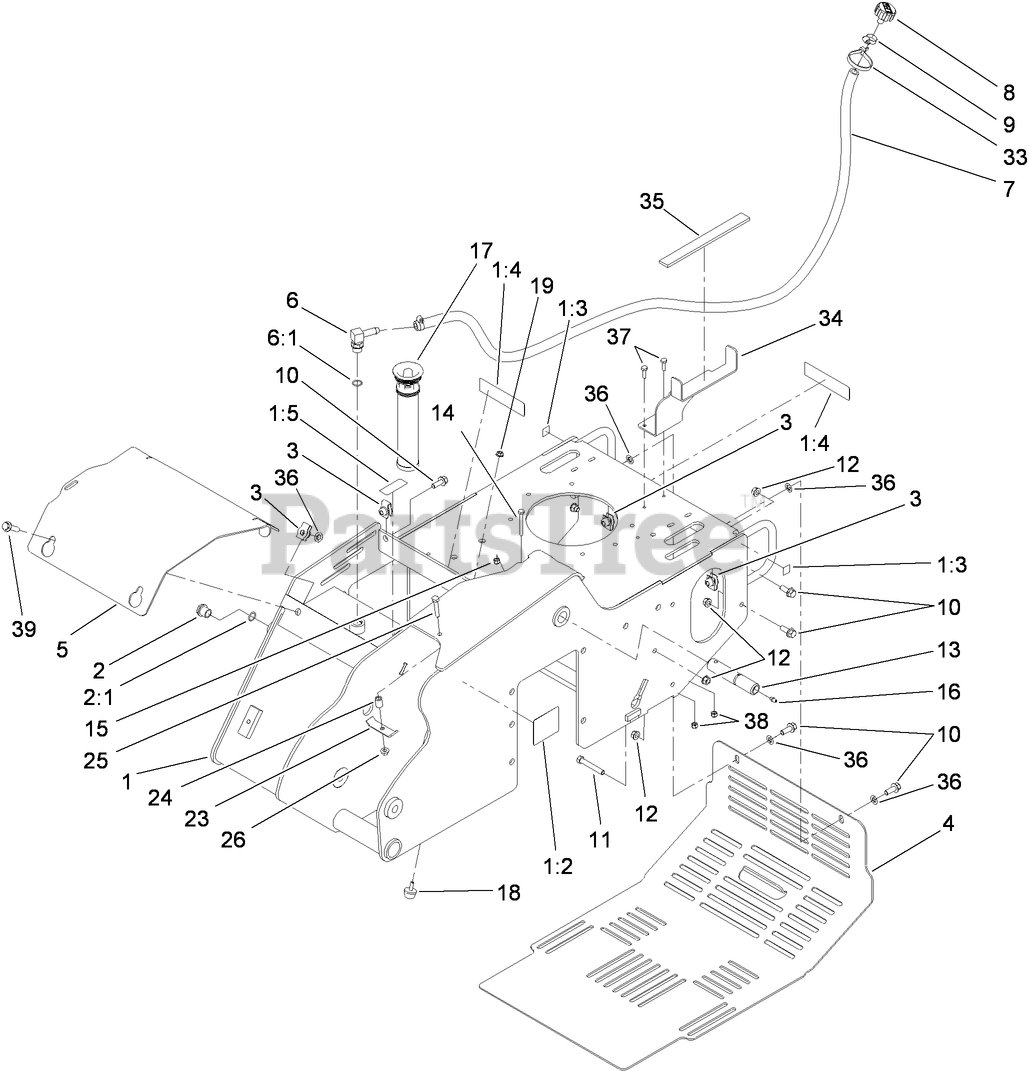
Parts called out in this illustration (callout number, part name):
1	MAIN FRAME ASM
1:2	DECAL-WARNING
1:3	DECAL-POINT, LIFT
1:4	DECAL-DANGER
1:5	DECAL-OIL, HYD
2	SIGHT GLASS ASM
2:1	O-RING
3	NUT-CLIP, U
4	COVER-REAR
5	PLATE-COVER, FRONT
6	FITTING-ELB 90
6:1	O-RING
7	HOSE-BREATHER
8	BREATHER
9	CLAMP-HOSE
10	SCREW-HHF
11	SCREW-HH
12	NUT-FLANGE
13	PIN-PIVOT
14	SCREW-HH
15	NUT-LOCK, NI
16	FITTING-GREASE
17	IN-TANK FILTER ASM
18	BUMPER
19	NUT-HF
23	BRACKET-CLAMP
24	SPACER
25	SCREW-HH
26	NUT-HF
33	TIE-CABLE
34	BRACKET-FUEL TANK
35	PAD-FOAM
36	NUT-PUSH
37	SCREW-HH
38	NUT-LOCK, NI
39	SCREW-HHF
